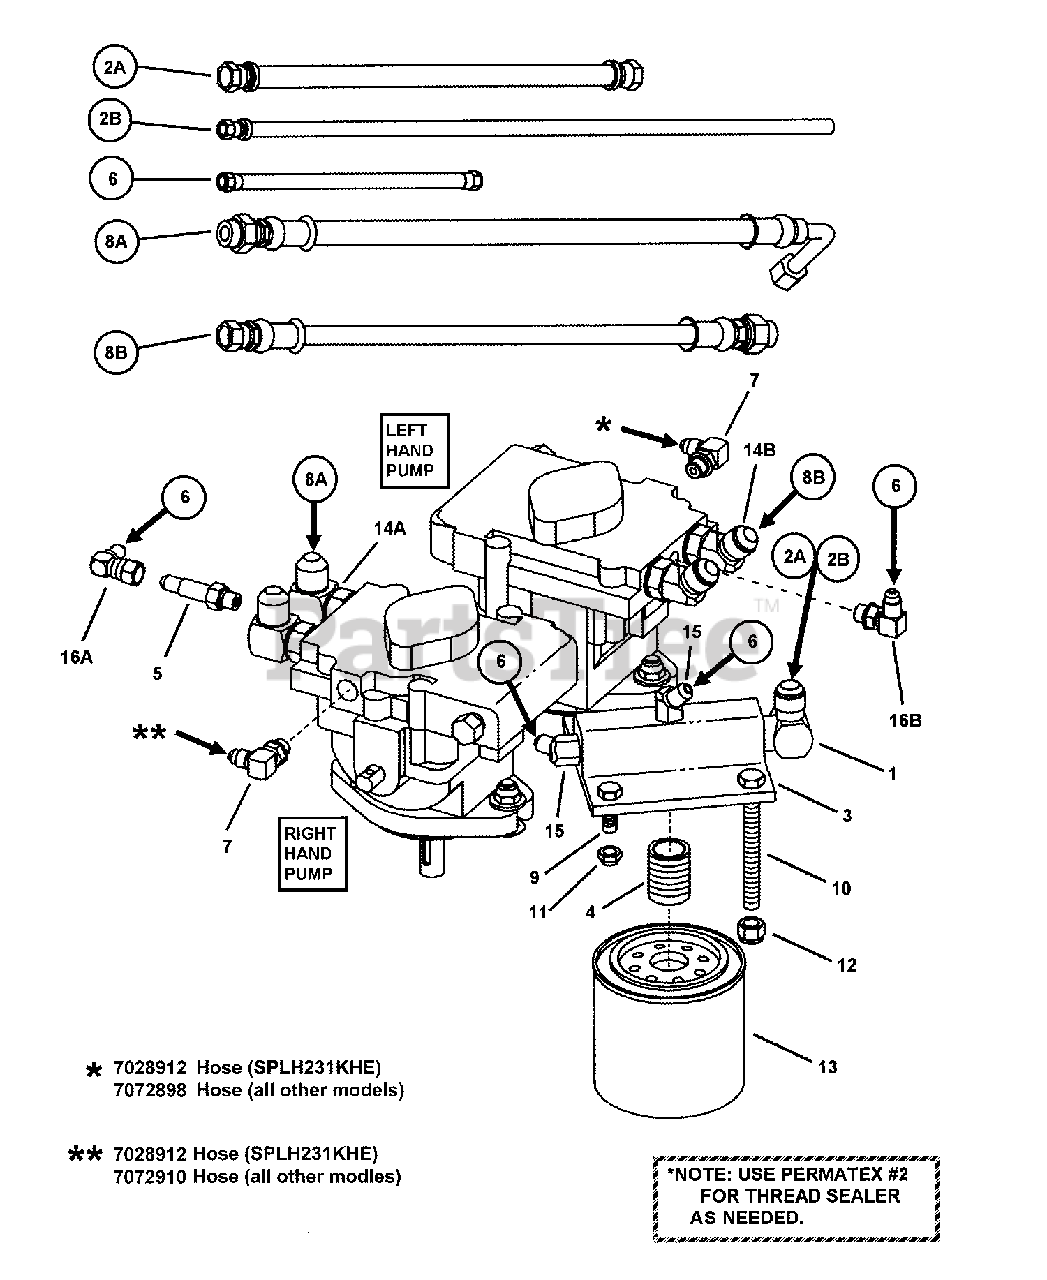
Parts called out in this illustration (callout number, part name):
1	FITTING, External 90 Degree w/37 Degree Flare
2A	HOSE, 1/2 x 16-1/2" Long (3/4-16 Female Thread, Both Ends)
2B	HOSE, 1/2 x 16-1/2" Long (7/16-20 Thread)
3	MOUNT, Oil Filter
4	FITTING, 7/16-20 Straight
5	FITTING, 7/16-20 Straight w/"O"-Ring
6	HOSE, 10-1/2" Long (7/16-20 Female Thread)
7	FITTING, 90 Degree- "O"-Ring Boss
8A	HOSE, Pump/Motor High Pressure, 24-1/2"
8B	HOSE, Pump/Motor, High Pressure 21-1/2"
9	BOLT, 5/16-18 X 1 GD5 YZ
10	BOLT, 3/8-16 x 3-1/2" Hex Head, GR 5
11	NUT, 5/16-18 Hex Top Lock, GR B
12	NUT, 3/8-16 HEX NYLON LOCK
13	OIL FILTER
14A	FITTING, 90 Degree w/"O"-Ring Boss
14B	FITTING, 45 Degree w/SAE "0"-Ring Boss
15	FITTING, External 45 Degree w/37 Degree Flare
16A	FITTING, 90 Degree w/37 Degree Swivel
16B	FITTING, 90 Degree w/"O"-Ring Boss
